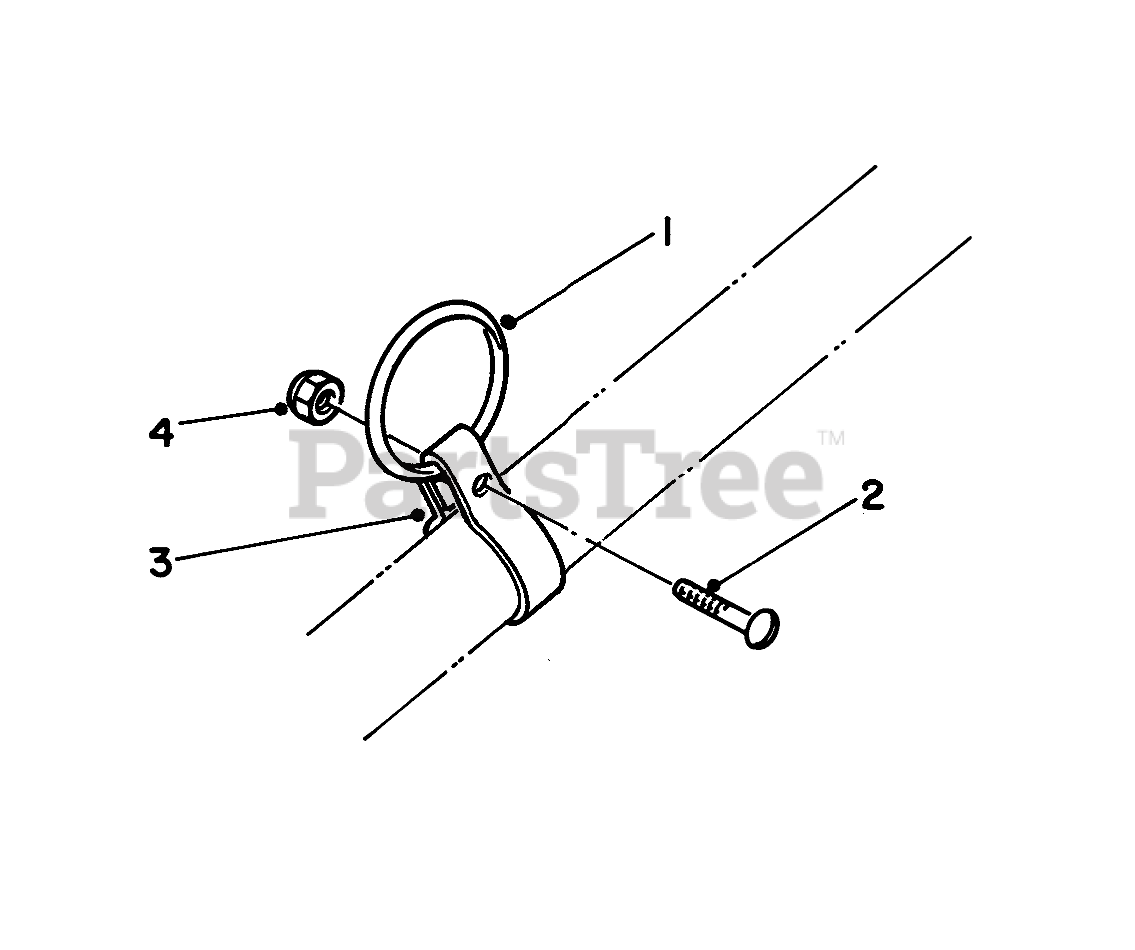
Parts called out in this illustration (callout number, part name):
1	RING-HARNESS
2	SCREW-SRH
3	HARNESS CLAMP
4	NUT-LOCK, NI
